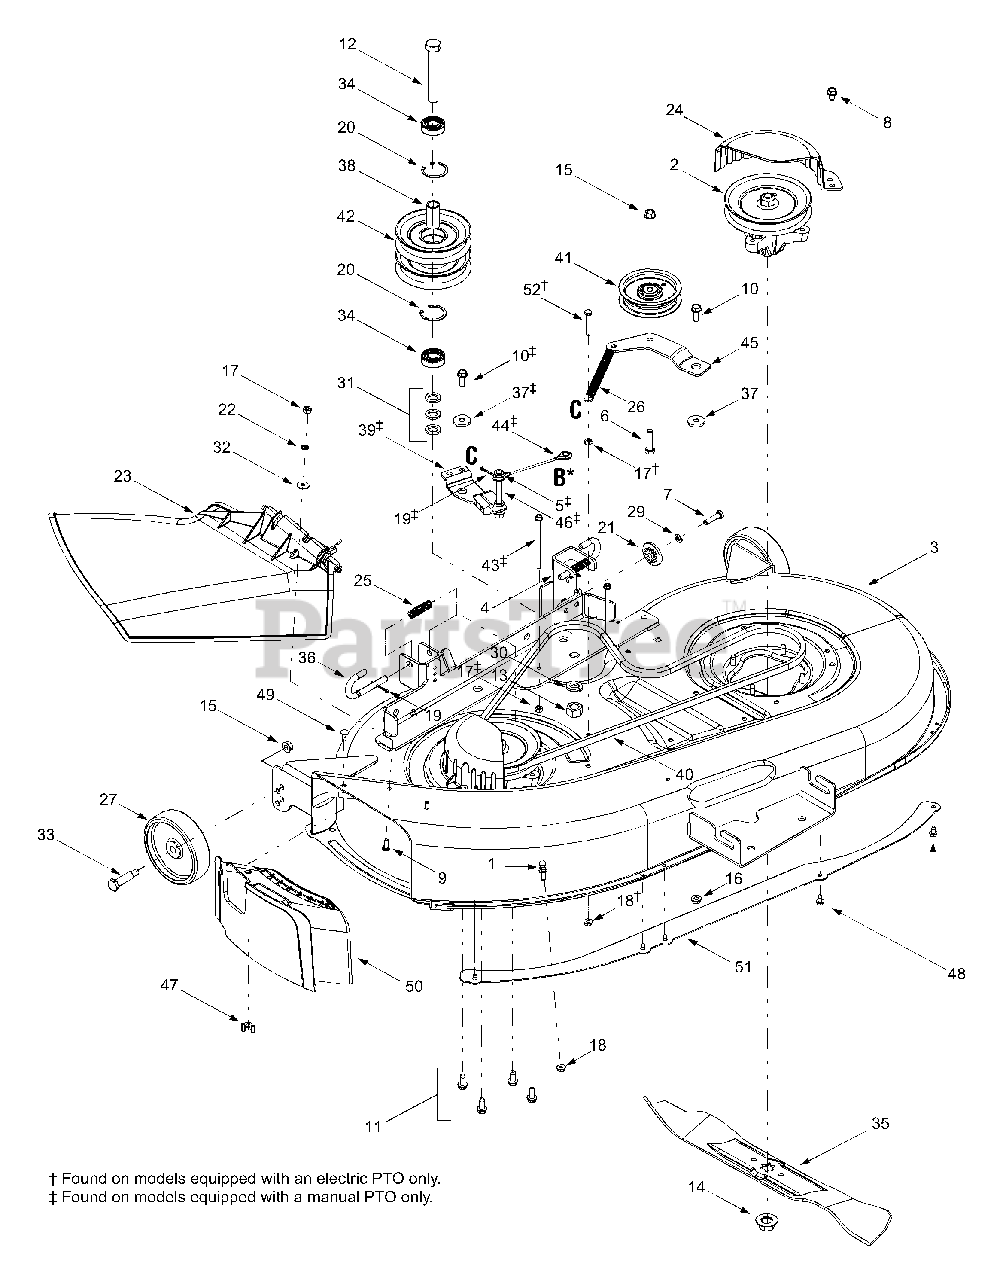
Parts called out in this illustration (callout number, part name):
1	Grass Catcher Pin
2	Spindle Assembly, 5.75 Dia.
5	Flat Washer,.385 x.62 x.063
6	Hex Cap Screw, 1/4-20 x 1.5
7	Hex Cap Screw, 5/16-18 x 1.25
8	Self-tapping Screw, 5/16-18 x.75
9	Hex Cap Screw, 1/4-20 x.62
10	Hex Head Washer Screw, 5/16-18 x.875
11	Self-tapping Screw, 5/16-18 x.75
12	Hex Cap Screw, 5/8-18 x.875
13	Hex Nut, 5/8-18
14	Hex Flange Nut, 5/8-18
15	Flange Lock Nut, 3/8-16
16	Flange Lock Nut, 5/16-18
17	Hex Nut, 1/4-20
18	Hex Flange Lock Nut, 1/4-20
19	Cotter Pin, 1/8 x 1.25
20	Internal Snap Ring
21	Deck Adjustment Gear
22	Push Nut.25 x.5
23	Side Discharge Chute Assembly
24	Belt Cover
25	Compression Spring,.406 x.531 x 1.75
26	Extension Spring,.50 x 4.74
27	Deck Wheel, 5 x 1.38
29	Lock Washer, 5/16
30	Lock Washer, 5/8
31	Flat Washer,.64 x 1.0 x.12
32	Bell Washer,.265 x.75 x.062
33	Shoulder Screw,.498 x 1.53
34	Bearing,.625 x 1.574 x.470
35	Three-in-one Blade, Star Center, 21.23"
36	Deck Release Pin
37	Shoulder Spacer,.625 x.324
38	Spacer,.635 x.88 x 1.72
39	Deck Brake Assembly
40	Deck Belt
41	Idler Pulley, 3.5
42	Double Pulley, 5.0
43	Self-tapping Screw, 1/4-20 x 4.0
44	Brake Cable, 5.05
46	Pin, 3/8-16, 3/8 x 3.27
47	Wing Nut, 1/4-20
48	Self-tapping Screw, 1/4-20 x.5
49	Carriage Screw, 1/4-20 x.62
50	Mulch Plug
52	Hex Cap Screw, 1/4-20 x 1.75
